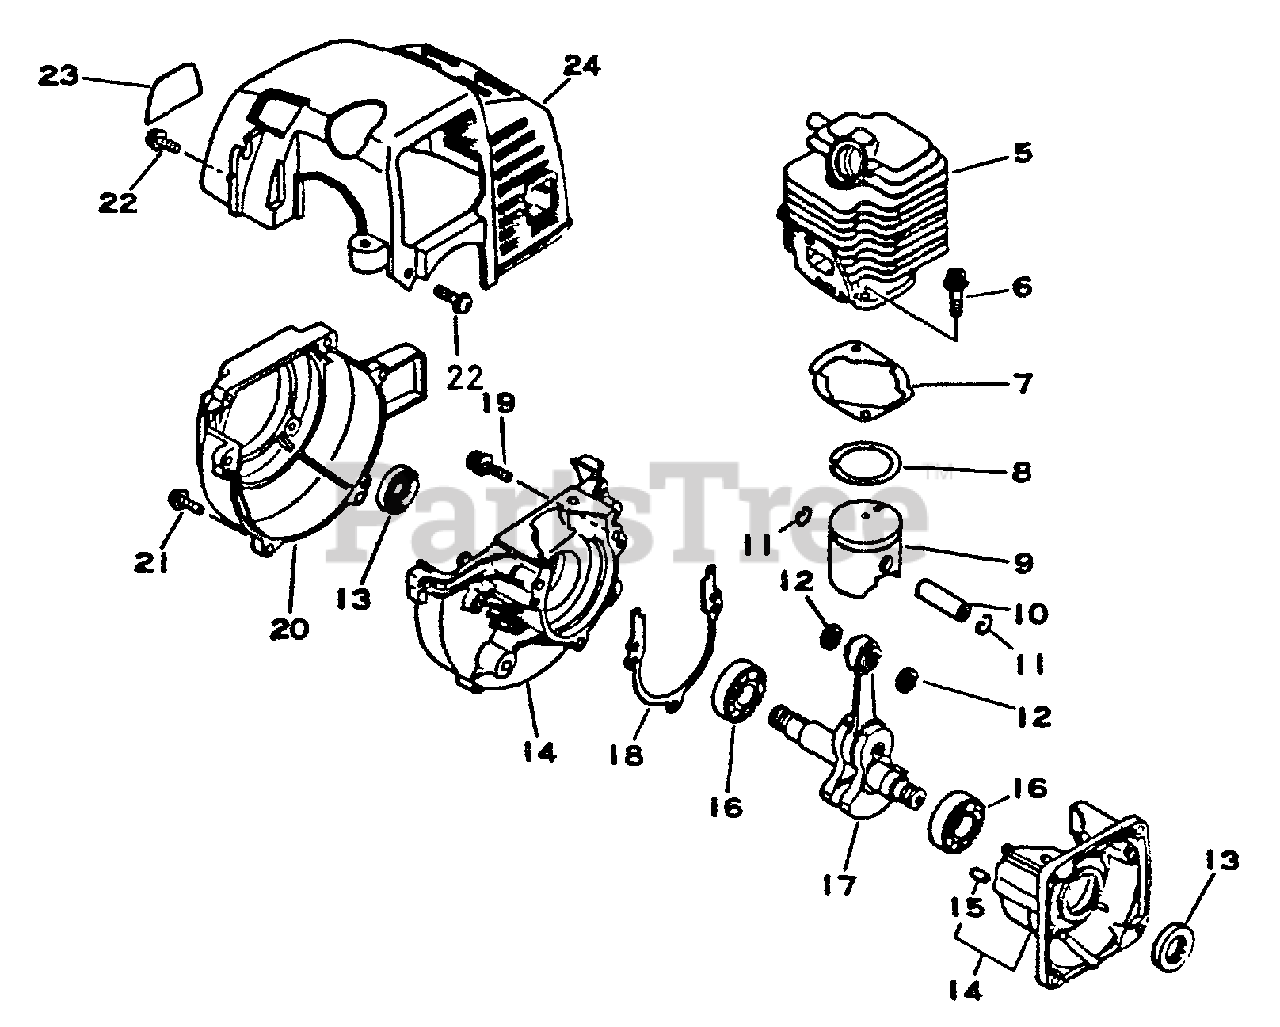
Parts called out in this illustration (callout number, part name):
5	CYLINDER
6	SCREW - 5X22
7	GASKET, CYLINDER
8	RING, PISTON
9	PISTON
10	PIN, PISTON
11	RING, RETAINING
12	SPACER, PISTON
13	SEAL, OIL
14	CRANKCASE KIT
15	PIN - LOCATING
16	BEARING, BALL - 6201
17	CRANKSHAFT ASSY
18	GASKET, CRANKCASE
19	SCREW - 5X25
20	CASE, FAN - ORANGE
21	SCREW - 4X16
22	SCREW - 4X12
23	LABEL - MODEL
24	COVER, ENGINE
